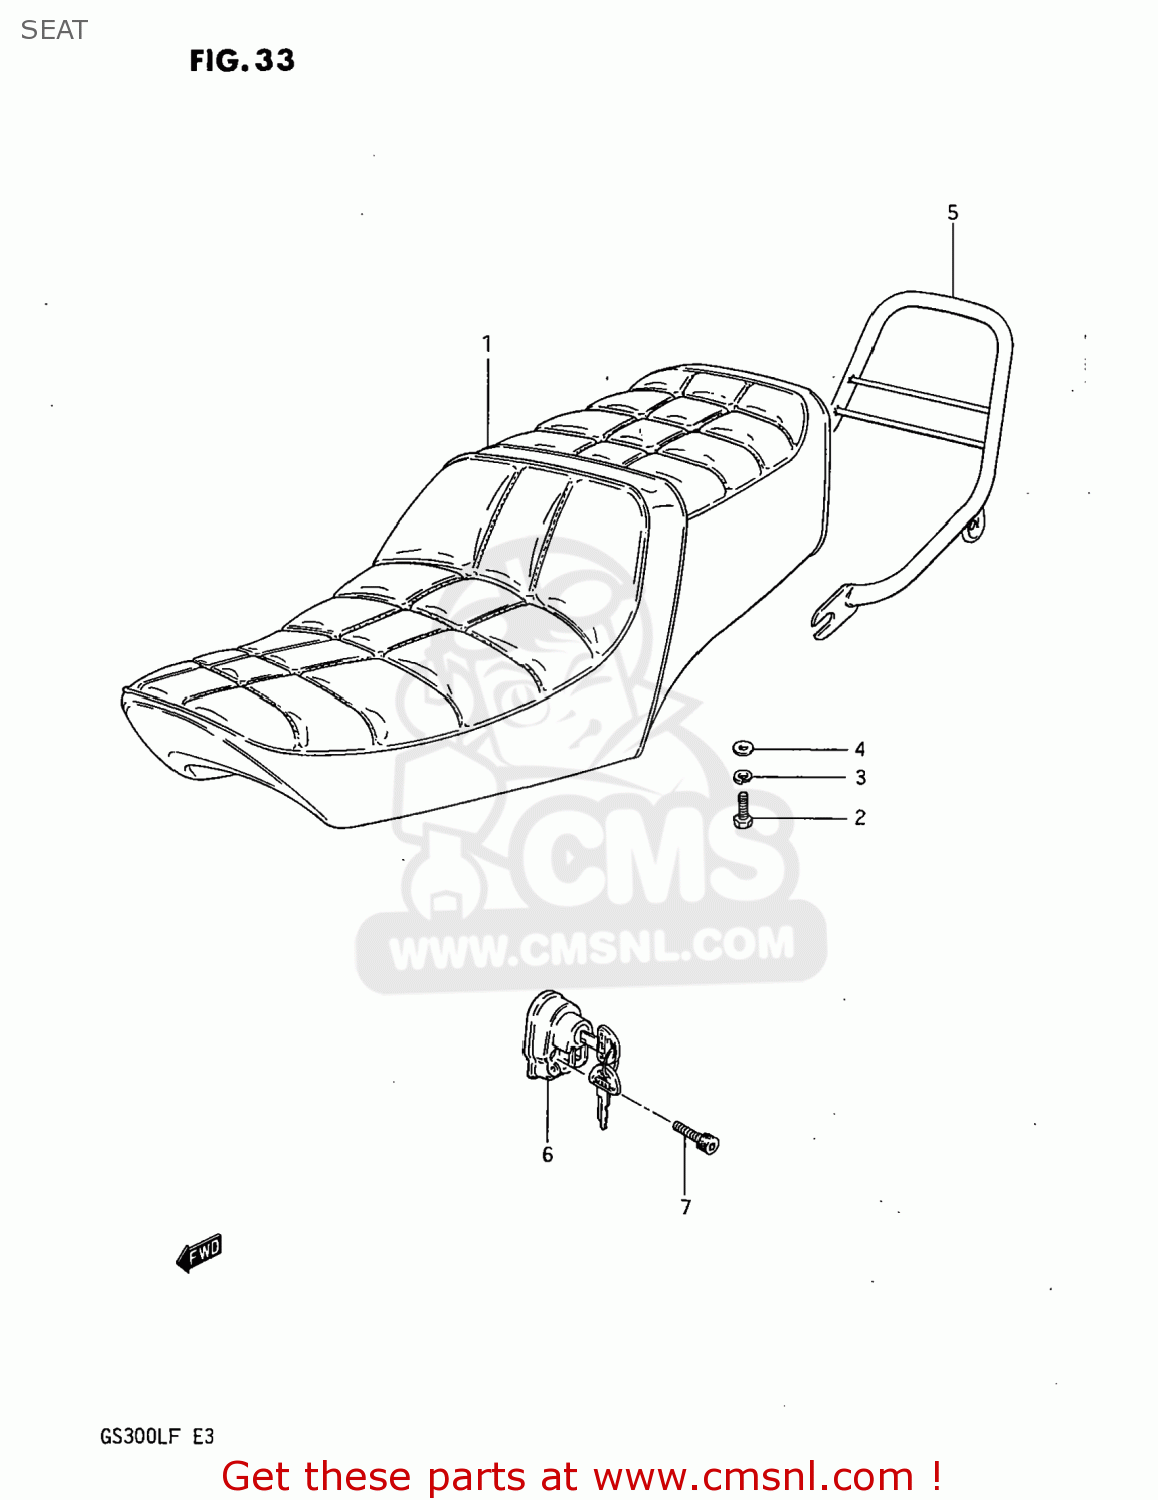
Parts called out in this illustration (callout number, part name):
1	SEAT ASSEMBLY
2	BOLT(6X20)
3	LOCK WASHER
4	WASHER
5	HANDLE,PILLION RIDER
6	LOCK ASSY,HELMET
8	BOLT
